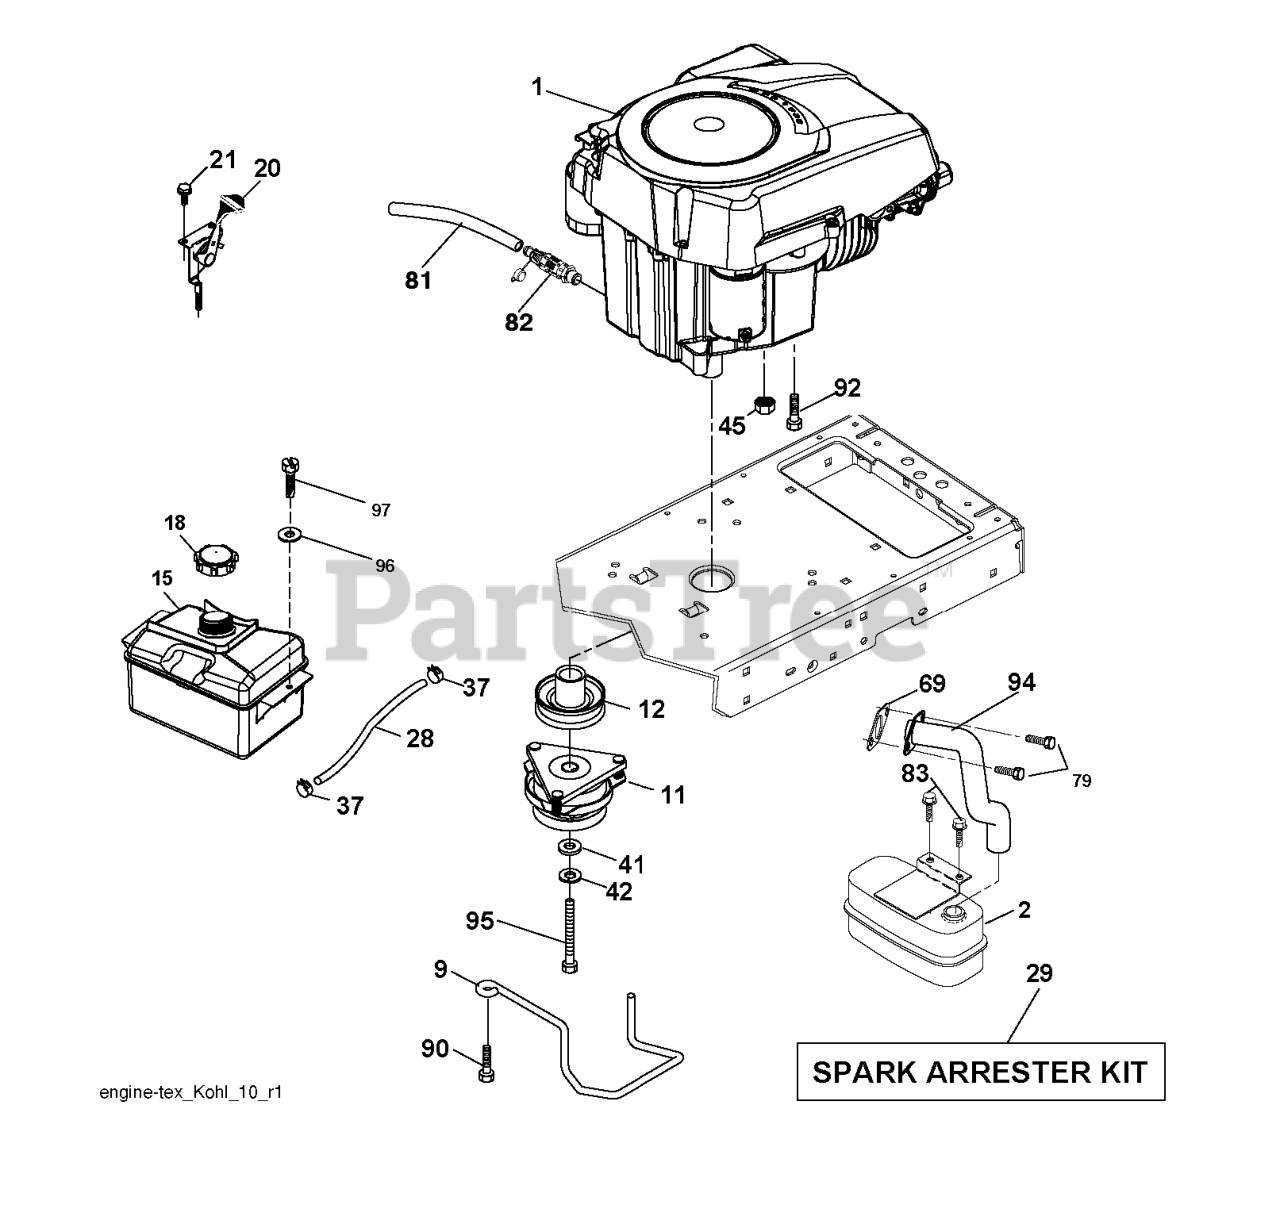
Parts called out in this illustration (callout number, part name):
1	MOWER HOUSING, DECK
2	RP BOLT 5/16-18 X3/4 ZN/YEL GR
5	RETAINER-SPRNG RB
6	BAR.SWAY.92.CRD
8	BOLT.3/8-24X1.25 GR8
9	LOCKWASHER
10	WASHER.BLADE
13	SHAFT ASM VENT
14	HOUSING.MANDREL.VENTED (MACHD)
17	BOLT.3/8-14X1.25
19	BOLT SHD 5/16-18
20	BOLT.3/8-24X1.25GR8. LHTHRD
21	LOCKNUT
26	BRACE.SUPT.SUSP.FRT.CRD
30	SCREW, WASHER HEAD
31	WASHER.SPACER.MANDREL
32	PULLEY, MANDREL
33	NUT, FLG TOPLOCK 9/16"
36	PULLEY.IDLER.4.25
41	NUT LOCK FLG 3/8-16 UNC
45	COVER.MANDREL.RH.CRD
46	SCREW.1/4-20X5/8
56	SPACER.RETAINER.MOWER
61	SPRING.TENSION.BELT
68	HEX-BELT
69	SHAFT.ASM.W/LWR.BRG.RH.THREAD
84	KEEPER, BELT IDLER
116	SHOULDER BOLT
117	WHEEL GAGE DONUT
118	LOCKNUT
119	WASHER.5/16.FLAT.STE.STD.
124	BOLT.3/8-16X1.50
130	BOLT.CARR.SQNK.5/16-18UNC.X3/4
131	CHUTE BAGGER
